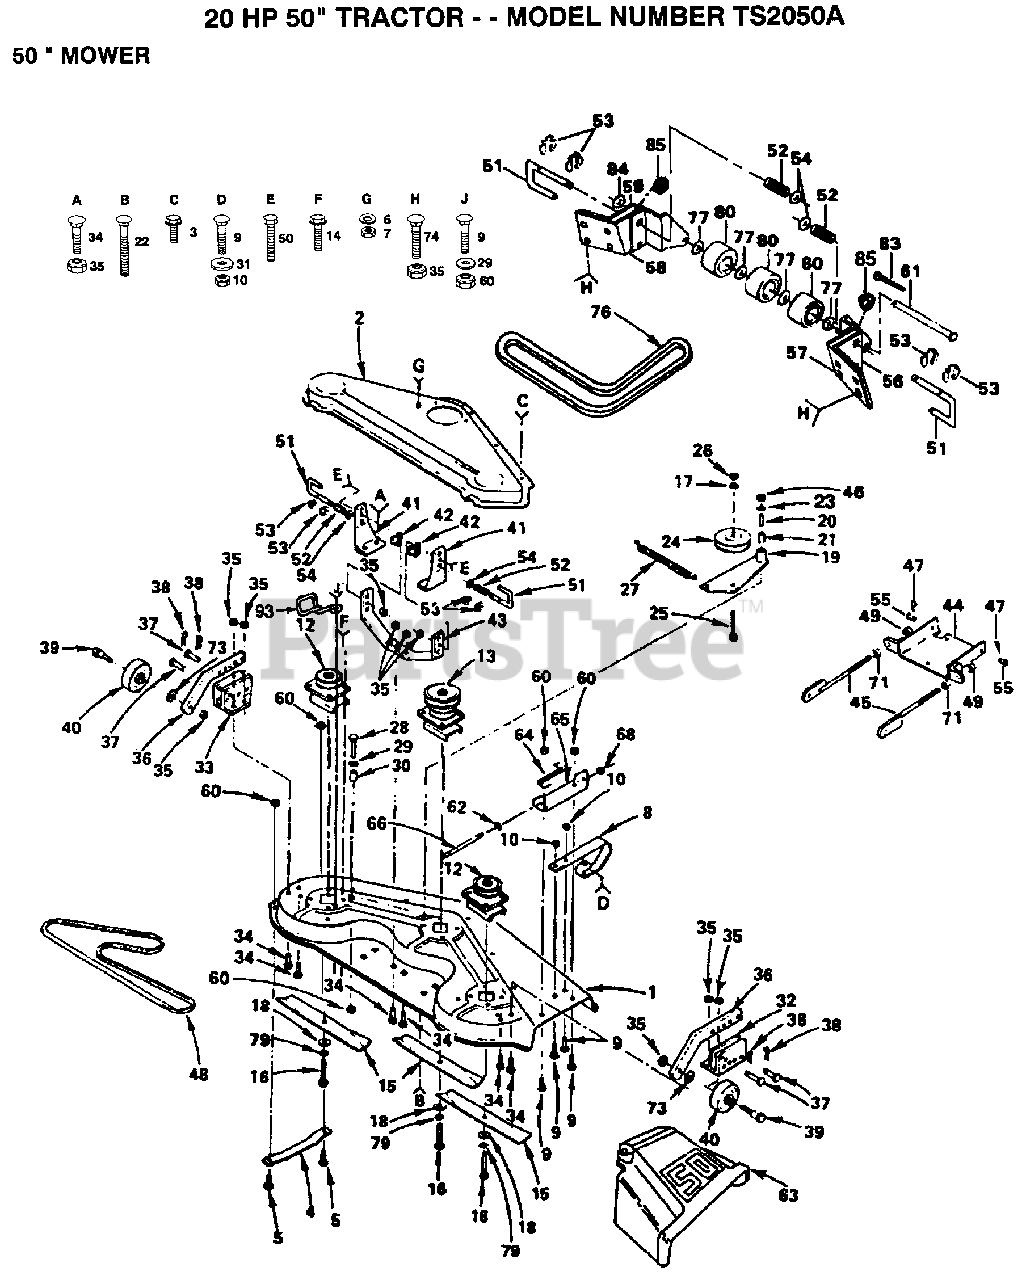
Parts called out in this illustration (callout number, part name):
2	CVR DRIVE DECK
3	SCREW LT
4	RUNNER-LH M
5	BOLT
6	LOCKWASHER
7	NUT.HEX.5/16-18
9	BOLT
13	JACKSHAFT
14	SCREW
15	"BLADE.50""STD.LIFT"
16	BOLT.3/8-24X1-1/2
17	LOCKWASHER
18	WASHER
19	ARM ASSY GT
22	BOLT
24	IDLER-FLAT T
26	NUT.HEX.3/8-16UNC
27	SPRING T
28	BOLT
29	WASHER M
30	SPACER SPLIT LT
31	WASHER
32	GUAGE WHL BRKT GT
33	GUAGE WHL BRKT GT
34	BOLT
36	GUAGE WHL BAR GT
39	BOLT M
40	WHEEL.GAGE.BLK.PL
41	SUSP BRKT GT
42	SPACER GT
43	SUSP BRACE GT
45	BRACKET.SUSPEN.AS
46	JAM NUT TI
47	RETAINER.SPRING
48	V-BELT M
49	NUT LTV
50	BOLT
51	RELEASE PIN GT
52	SPRING M
53	KLIP RING
55	CLEVIS PIN GT
56	BRACKET T
57	BRACKET T
58	BRACKET T
59	BRACKET T
61	PIVOT PIN T
62	WASHER
63	DEFLECTOR
66	ROD-HINGE T
68	NUT PUSH M
71	NUT
73	WASHER
74	BOLT
76	BELT-V.93.5.MWR
77	WASHER T
80	ROLLER T
83	COTTER PIN
85	SPACER T
93	BELT RETIANER
